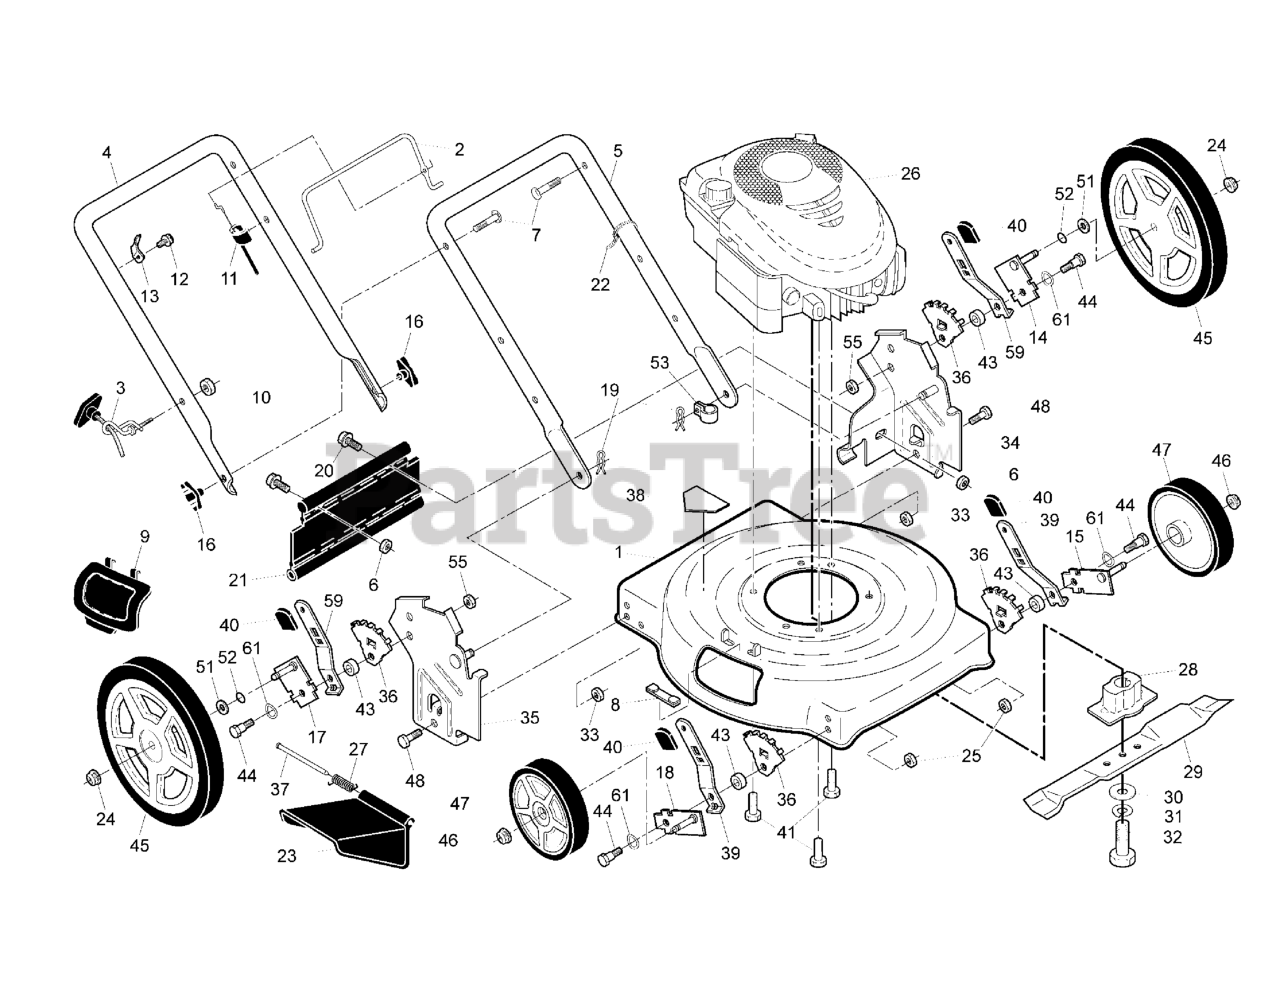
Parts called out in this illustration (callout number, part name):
1	Lawn Mower Housing
2	Control Bar
3	Rope Guide
4	Upper Handle
5	Lower Handle
6	Locknut, Hex 1/4-20
7	Handle Bolt 5/16-18
8	Clip, Closeout
9	Mulcher Plate
10	Nut, Hex 1/4-20
11	Engine Zone Control Cable
12	Hex Washer Head Screw #10-24 x 1/2
13	Up-Stop Bracket
14	Axle Arm Assembly, Rear, LH
15	Axle Arm Assembly, Front, LH
16	Handle Knob
17	Axle Arm Assembly, Rear, RH
18	Axle Arm Assembly, Front, RH
19	Hairpin Cotter
20	Screw, Hex Cap Head 1/4-20
21	Rear Defl ector
22	Wire Tie
23	Discharge Guard
24	Nut, Hex, Flangelock 3/8-16
25	Nut, Hex, Flangelock 5/16-18
26	* ENGINE, Briggs & Stratton
27	Torsion Spring
28	Blade Adapter
29	22" Blade
30	Hardened Washer
31	Helical Lockwasher 3/8
32	Screw, Hex Head, Grade 8, 3/8-24 x 1-3/8
33	Nut, Hex, Nylock 5/16-18
34	Wheel Bracket Support, LH
35	Wheel Bracket Support, RH
36	Wheel Bracket Adjuster
37	Hinge Rod
38	Danger Decal
39	Selector Spring, Front
40	Selector Knob
41	Screw, Hex Head, Threaded, Rolled 3/8-16 x 1
43	Spacer
44	Shoulder Bolt 5/16-18
45	Wheel & Tire Assembly, Rear, 12"
46	Nut, Hex, Flangelock 3/8-16
47	Wheel & Tire Assembly, Front, 8"
48	Bolt, Hex Head 5/16-18
51	Washer, Flat 3/8
52	O-Ring
53	Clip, Cable
55	Nut, Hex
59	Selector Spring, Rear
61	Washer, Curved, Cylindrical
